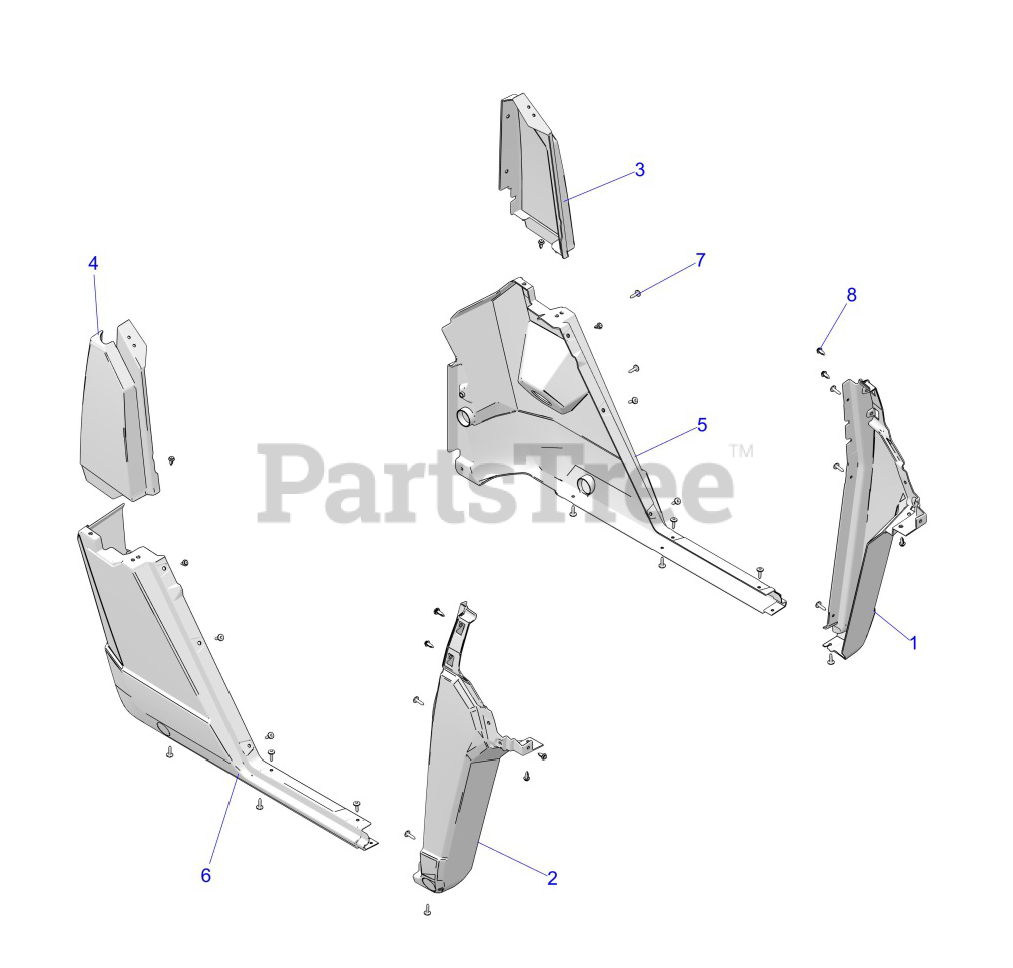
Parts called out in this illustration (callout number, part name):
1	COVER,FRONT,LH,BLK
2	COVER,FRONT,RH,BLK
3	FENDER-REAR,UPPER,LH,BLK
4	FENDER-REAR,UPPER,RH,BLK
5	COVER-ROCKER,LH,BLK
6	COVER-ROCKER,RH,BLK
7	SCR-TXTH-M6X1.0X25 RIE
9	RIVET-TUFLOK,.315-.325X.787 (5
